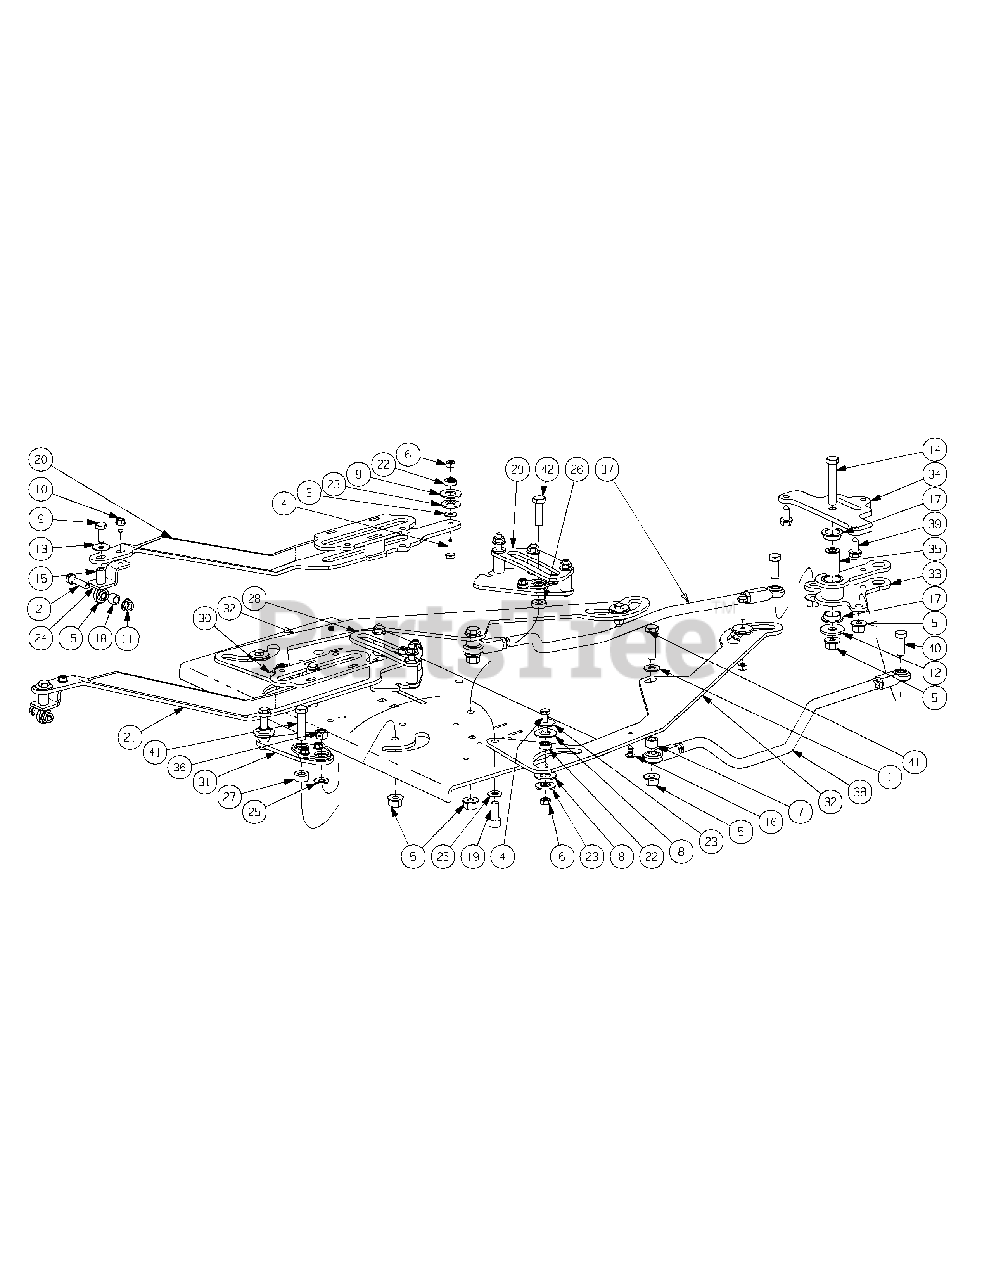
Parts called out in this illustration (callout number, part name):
1	Flat Washer, 3/8
2	HHCS, 5/16-18 x 1-1/4
3	Washer, .25 x .630 x .0515
4	HHCS, 1/4-20 x 1.00
5	Hex Nut, 3/8-16, Lock Flange
6	Nut, 1/4-NC, Side Lock
7	Spacer, .625 OD x .407 ID x .375
8	Slide Washer
9	HHCS, 5/16-24 x .75
10	Screw, TT, 1/4-20, 0.5, Hex Index Washer
11	Nut, Lock, HexFlange, 5/16-18
12	Washer, 1.25 x .411 x .100
13	Belle Washer, .325 x .930 x .045
14	HHCS, 3/8-16 x 2.25
15	Rod End, 5/16, RH
16	Rivet, 1/4 x 5/8
17	Flange Bearing, .752 x 1.125 x .305
18	Spacer, .334 x .500 x .375
19	Socket Head Cap Screw, 3/8-16 x .88
20	Pump Control Bracket Assembly, RH
21	Pump Control Bracket Assembly, LH
22	Ball Bearing, .25 ID x .625 OD x .196
23	Shoulder Spacer, .251 x 1.00 x .155
24	Support Rod End Bracket
25	Spacer, .381 x .750 x .040
26	Spacer, .381 x .750 x .150
27	Spacer, .381 x .750 x .312
28	Speed Control Cam Shaft, LH
29	Speed Control Cam Shaft, RH
30	Steering Pivot Assembly, LH
31	Steering Pivot Assembly, RH
32	Control Link Plate
33	Front Steering Pivot Assembly
34	Pivot Steering Mounting Plate
35	Spacer, .385 x .750 x 1.28
36	Hex Nut, 3/8-16, Center Lock
37	Control Rod Assembly, LH
38	Control Rod Assembly, RH
39	Self Tapping Screw 5/16-18 x .750
40	HHCS, 3/8-16 x 1.00
41	HHCS, 3/8-16 x 1.50
42	HHCS, 3/8-16 x 1.25
